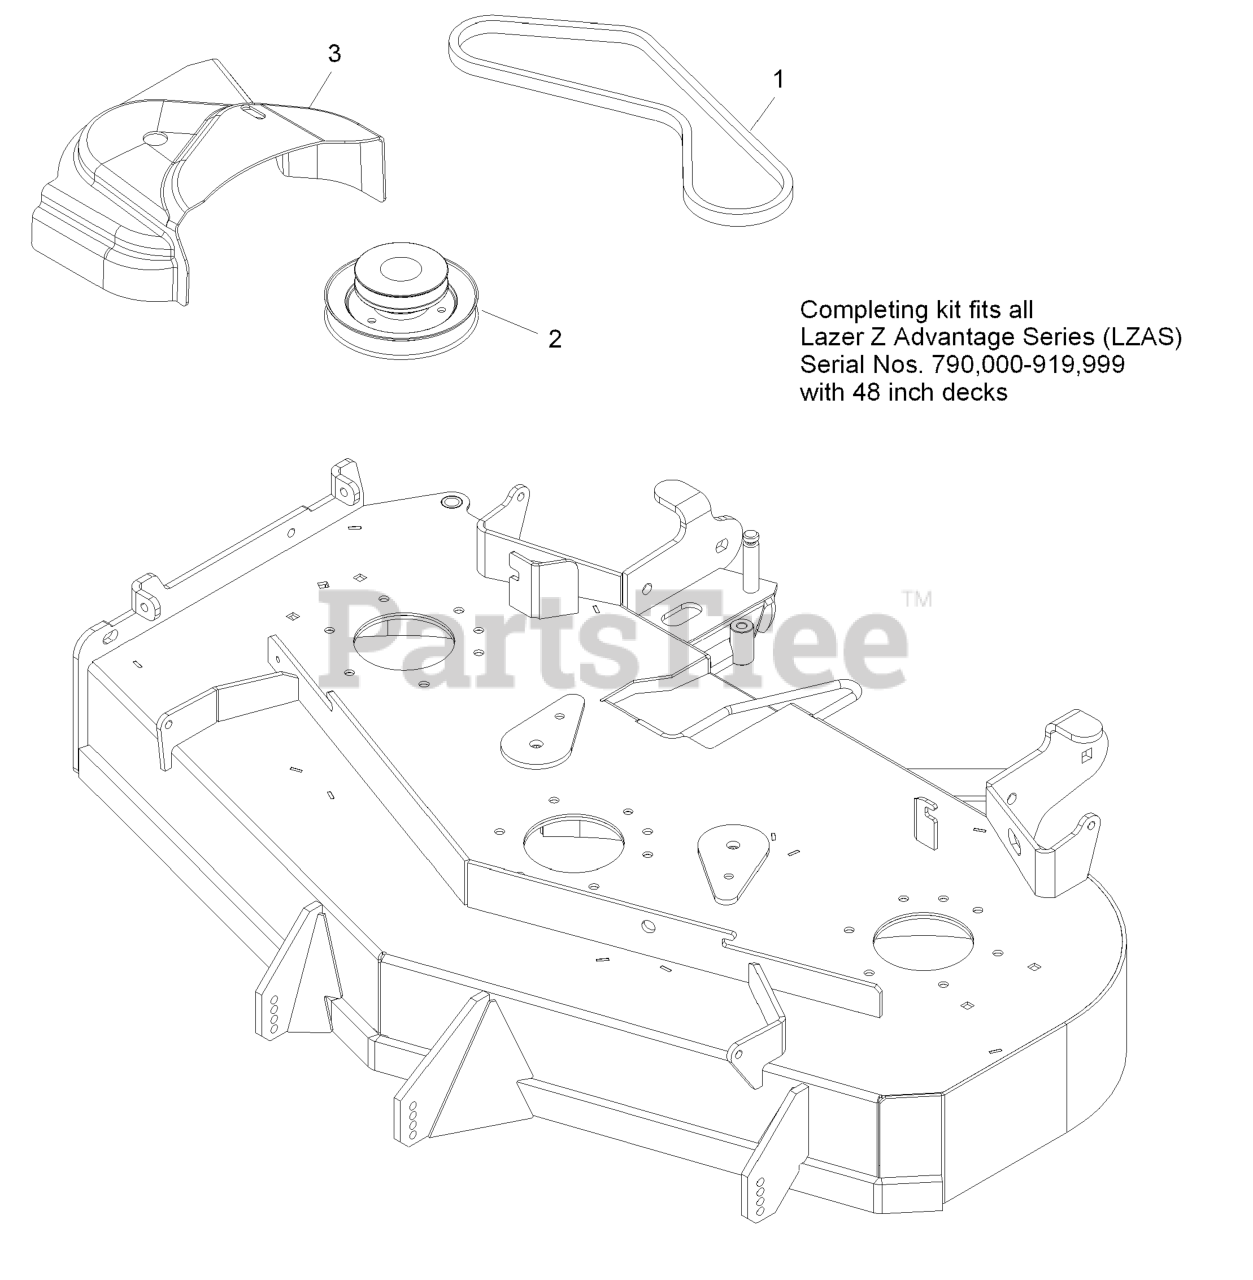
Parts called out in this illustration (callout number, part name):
1	Belt, Blower (48")
2	Jackshaft,Uv Drive 484
3	Cover,Belt Uv 48
